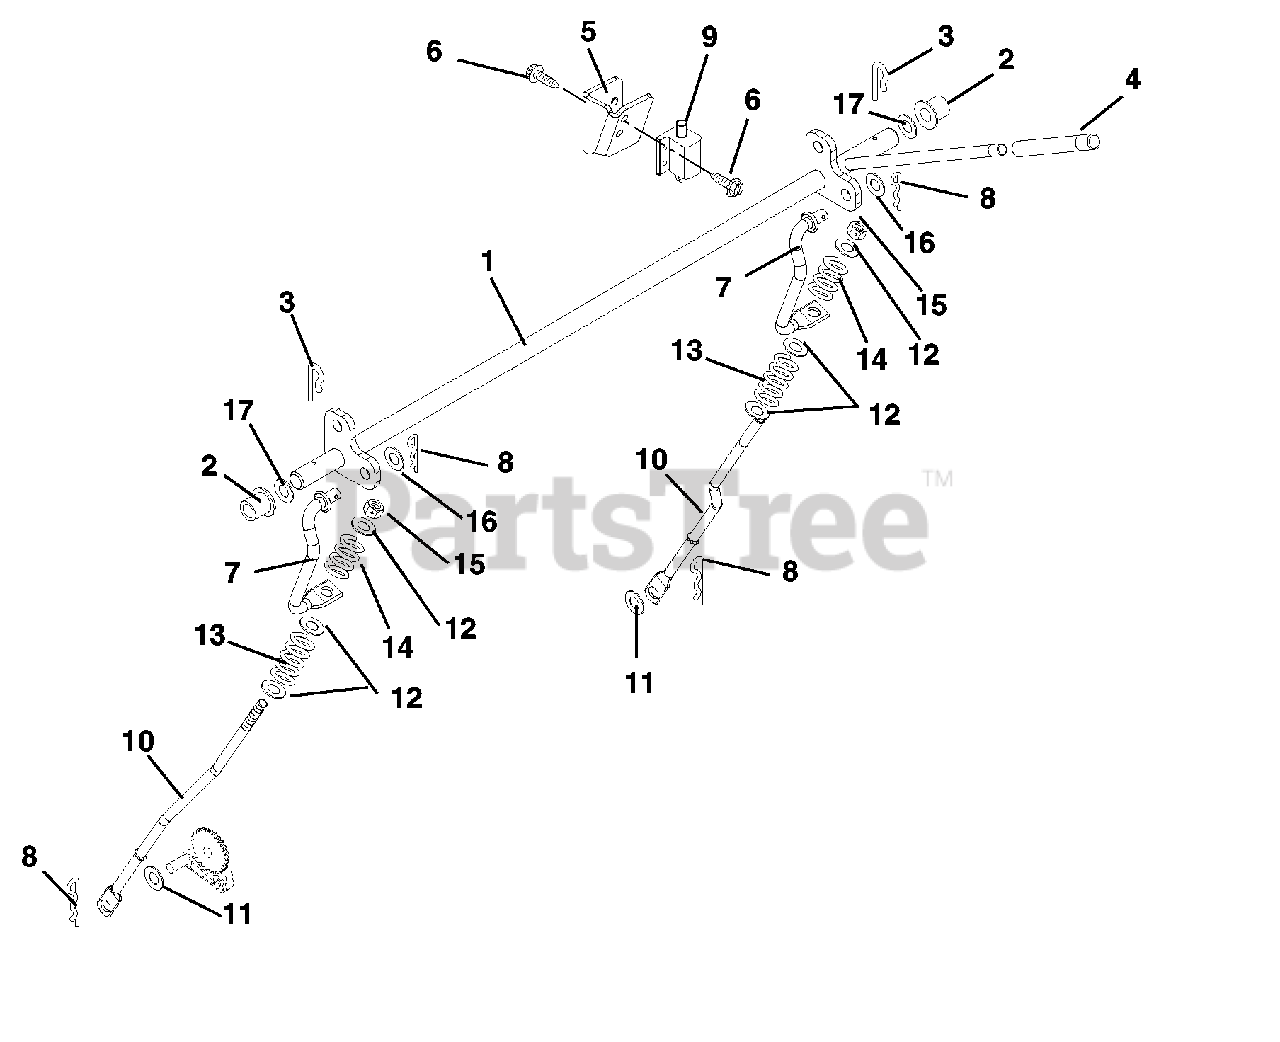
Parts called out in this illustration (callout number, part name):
1	WMT, ZOOM BRAKE ROD
2	BSHG-FLG .630X1.000X.625 NY
3	PIN, SPRING CLIP
4	GRIP,HAND CLUTCH LEVER
5	BRACKET, BRAKE SWITCH
6	@SCR-TAP 10-24X.50 HWH TR YWZC
7	ROD-OVER CENTER
8	PIN-HAIR, ENDRIES #25 YWZC
9	SWITCH, INTERLOCK NC
10	ROD-PARK BRAKE EZT
11	WSHR-FL-STL .406X1.00X.188 YWZ
12	@WSHR-FL-STL.344X.688X.065YWZC
13	SG-COMP .045X.50X1.187
14	SG-COMP .063X.53X1.187
15	@NUT-LK-NYL .312-18 YWZC
16	@WSHR-FL-STL.406X.812X.065 YWZ
17	WSHR-FL-STL .627X.990X.032
